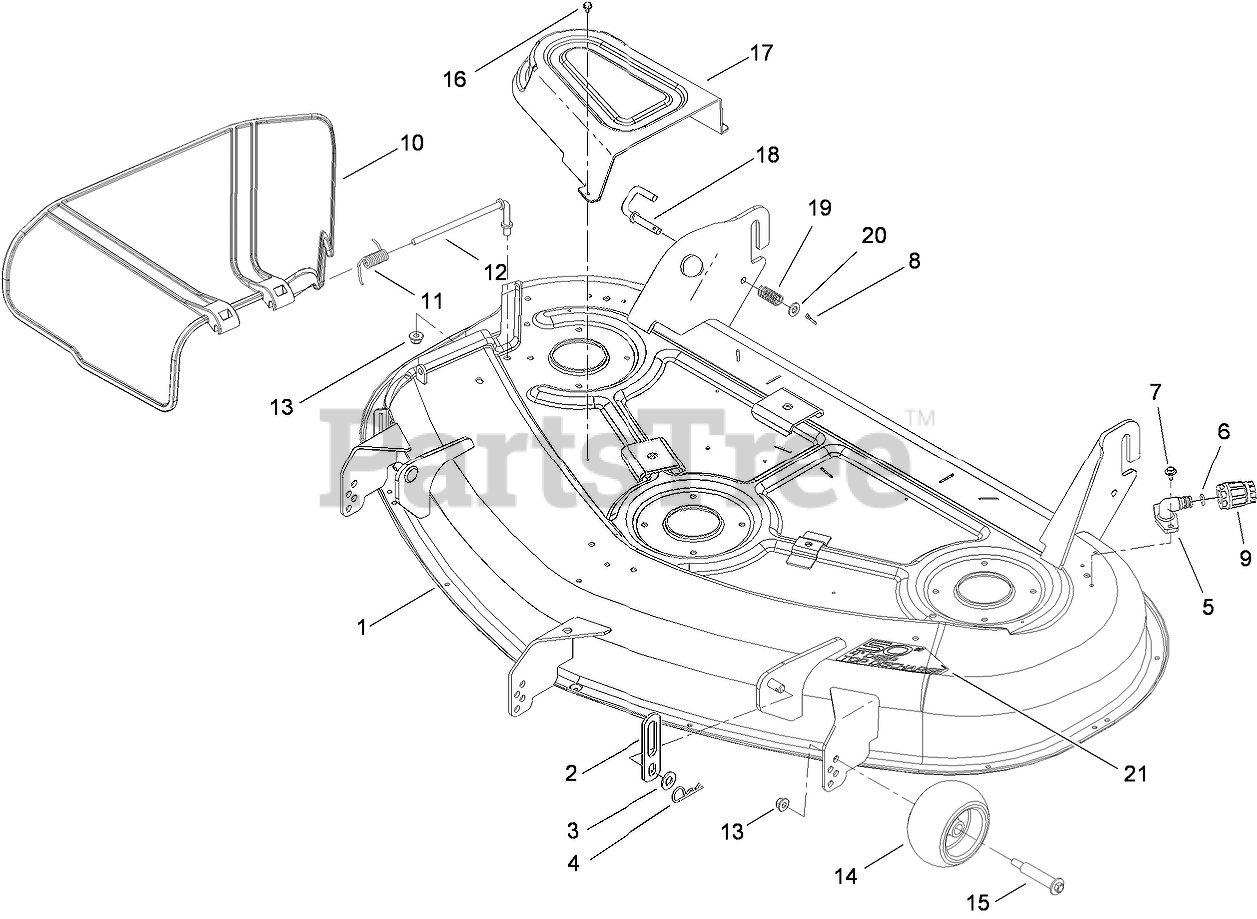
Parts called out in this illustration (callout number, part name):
1	50 INCH DECK ASM
2	LINK-LIFT
3	WASHER-FLAT
4	PIN-COTTER
5	FITTING-WASHOUT
6	O-RING
7	SCREW-HHFTF
8	PIN-COTTER
9	CONNECTOR-HOSE
10	DEFLECTOR
11	SPRING-TORSION
12	ROD-PIVOT
13	NUT-HF, NI
14	ROLLER-SCALP, ANTI
15	BOLT-SHOULDER
16	SCREW-HWHTF
17	COVER-BELT
18	PIN-LATCH
19	SPRING-COMPRESSION
20	WASHER-FLAT
21	DECAL-50 INCH
